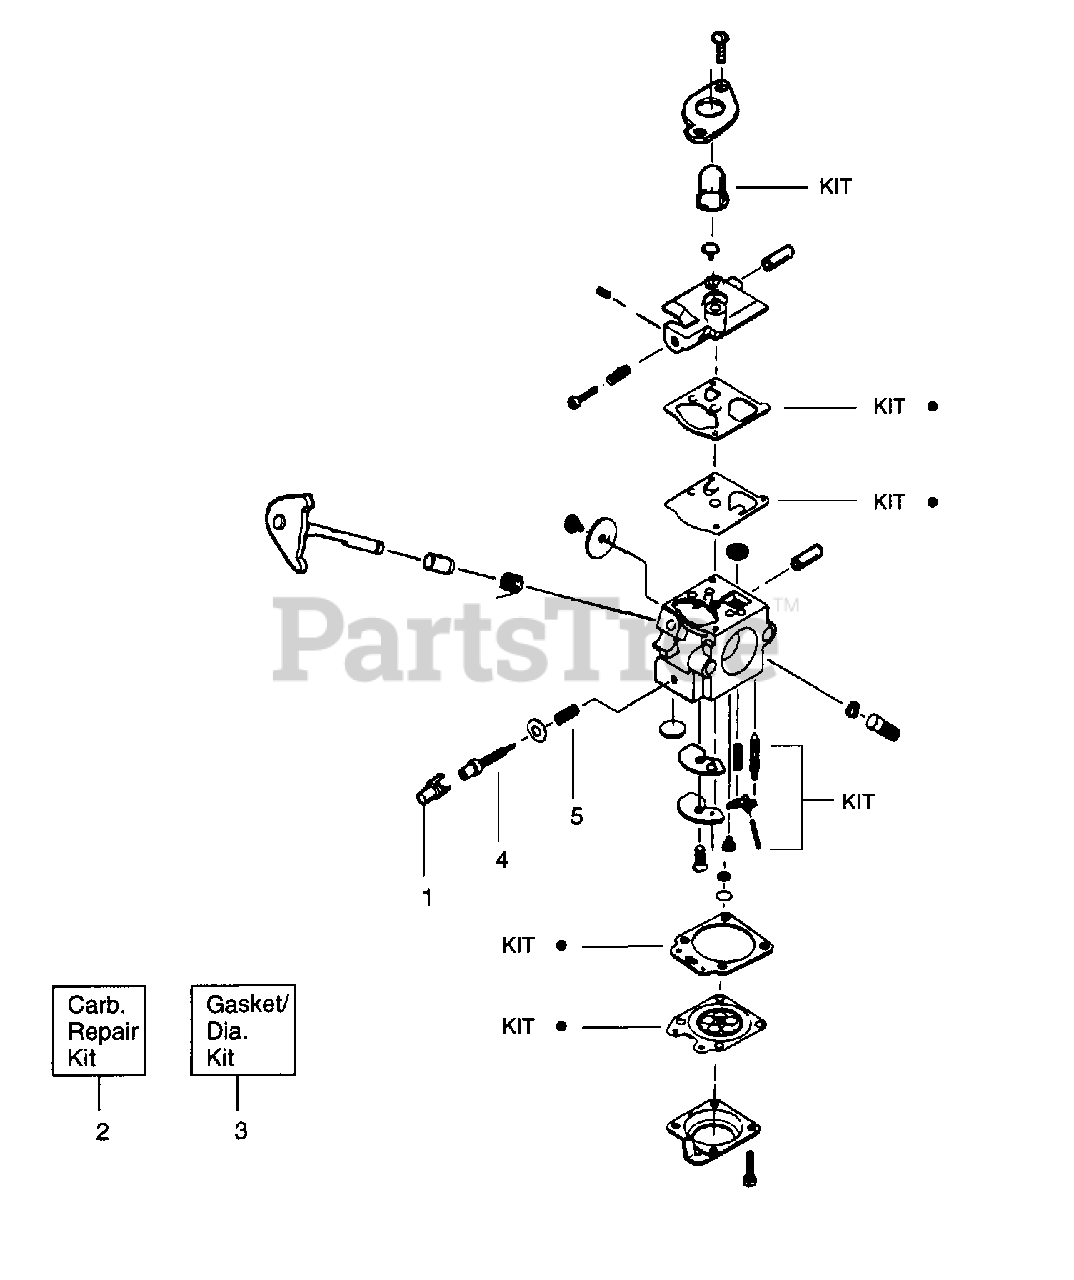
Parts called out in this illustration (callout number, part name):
1	Limiter Cap
2	Carburetor Repair Kit
3	Gasket Diaphragm Kit
4	Needle - Idle
5	Spring - Idle Needle
